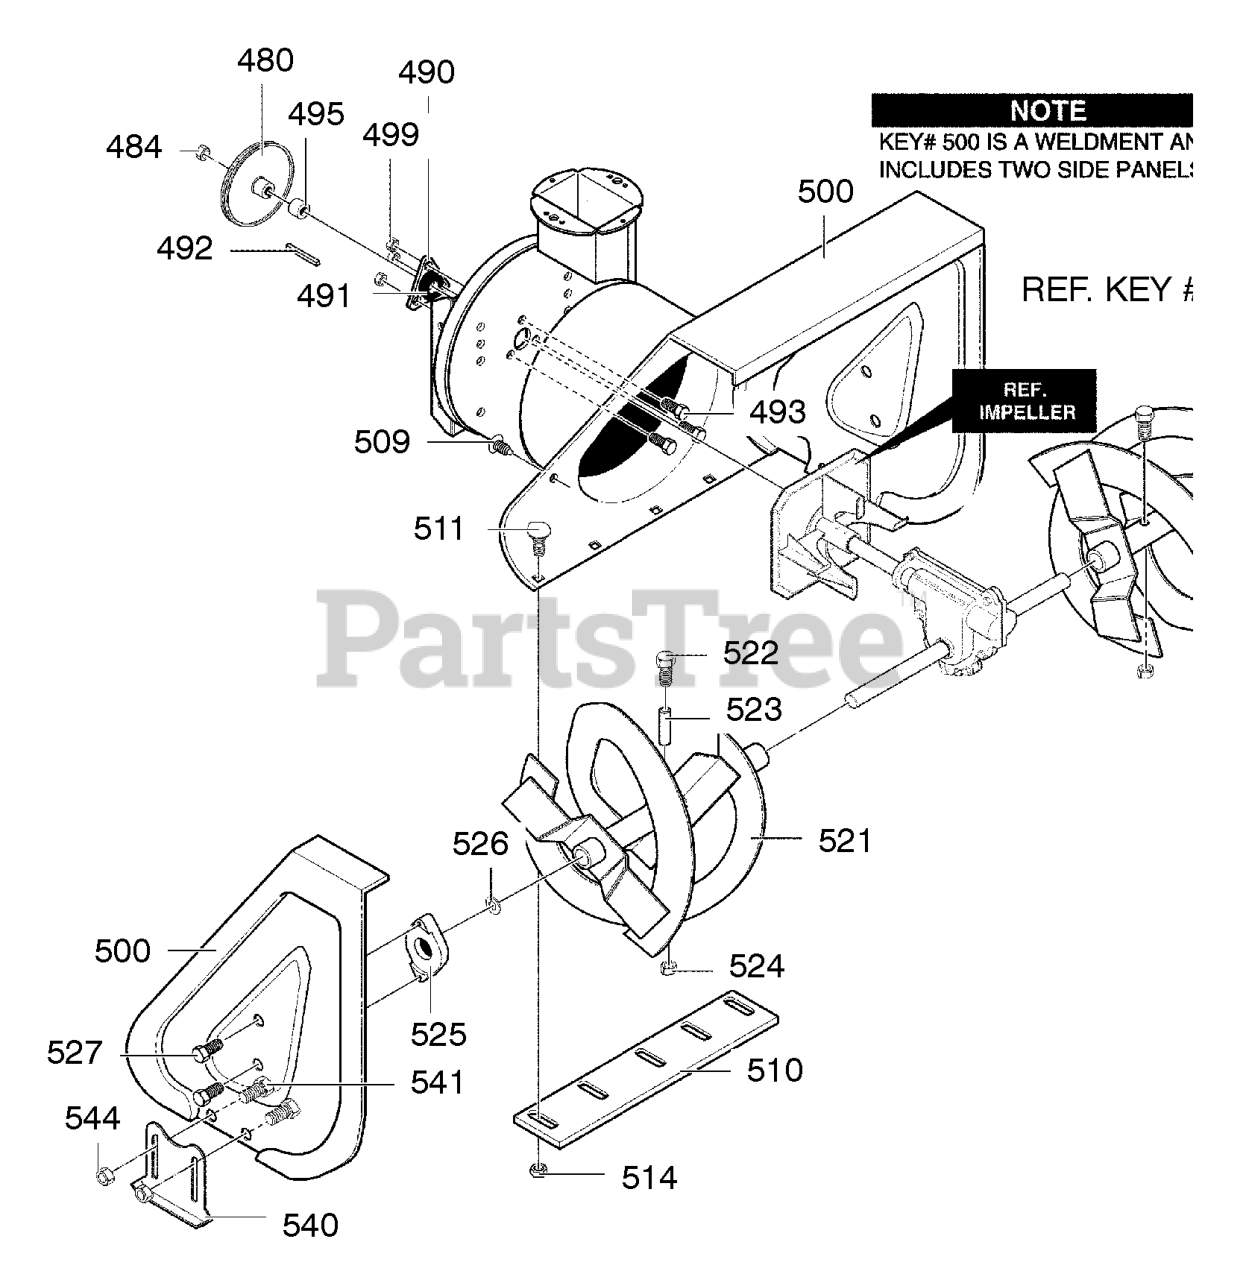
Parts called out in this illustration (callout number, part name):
484	NUT, 1/4-20
490	RETAINER, BALL BRNG
491	BEARING, BALL
492	KEY, SQUARE
493	BOLT, HEX - 0.31-18X0.50
495	SPACER, FRICTION PULLEY
499	NUT, 5/16-18 HEXWDFLLK
500	HOUSING, ASSY
509	PLUG, CHRISTMAS TREE
510	BLADE, SCRAPER
511	BOLT, 1/4-20X.75
520	AUGER, ASSY, LH
521	AUGER, ASSY, RH
522	SCREW, 1/4-20X1.75
523	SPACER, SLEEVE
524	NUT, 1/4-20
525	BEARING,FLANGE
527	SCREW, 5/16-18 x 0.75
540	SKID, HEIGHT ADJUST
541	BOLT, 5/16-18 X .75
544	NUT, 5/16-18 REGHEX
